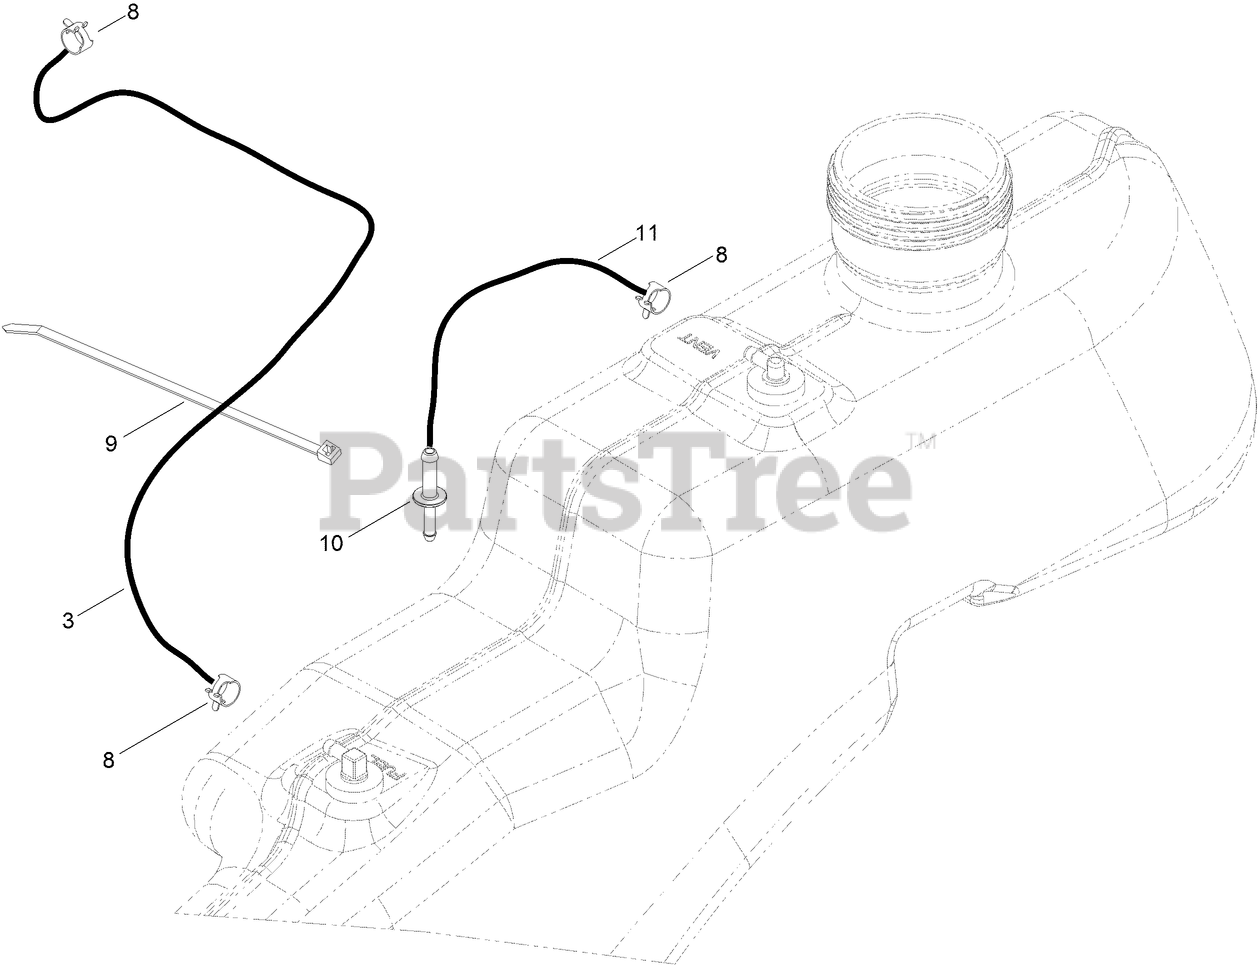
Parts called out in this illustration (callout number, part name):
3	HOSE-FUEL
8	CLAMP-HOSE
9	TIE-CABLE
10	ADAPTOR-ORIFICE
11	HOSE-FUEL
